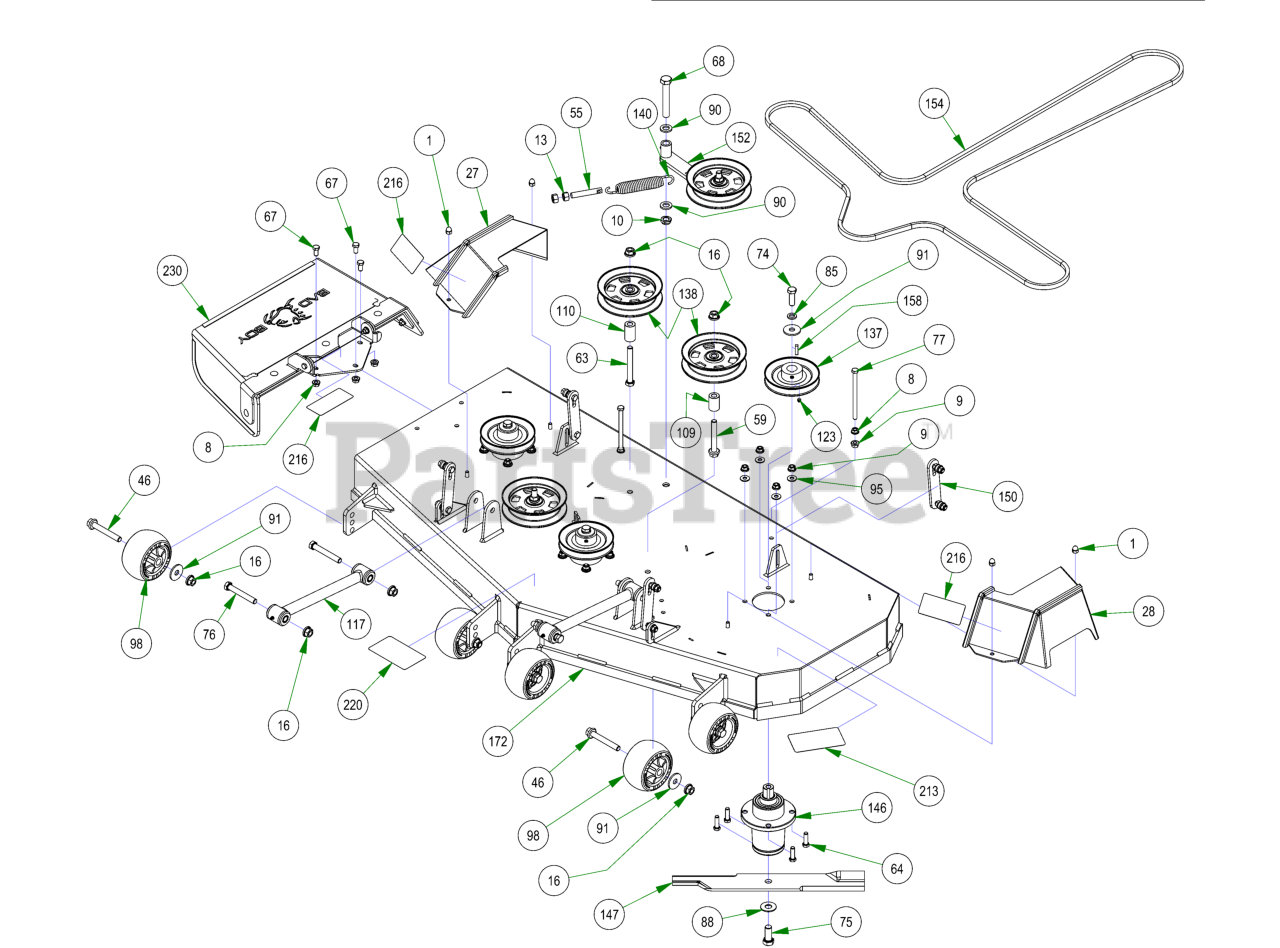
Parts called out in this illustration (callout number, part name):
1	5/16-18 ACORN NUT HIGH-CROWN ZC
8	3/8-16 HEX SERRATED FLANGE NUT HARD/ZINC
9	3/8-16 NYLON INSERT FLANGE LOCKNUT (GR.F) ZINC
10	5/8-11 NYLON INSERT JAM LOCKNUT ZINC
13	1/2-13 HEX NUT ZINC
16	1/2-13 NYLON INSERT FLANGE LOCKNUT ZINC
27	2021 Maverick 54”/60” RH Pulley Cover
28	2021 Maverick 54”/60” LH Pulley Cover
46	1/2-13 X 90MM HEX FLANGE BOLT W/SHOULDER (GR.8) ZINC
55	All Thread
59	1/2-13 X 3-1/2 HEX FLANGE BOLT (GR.8) ZINC
63	1/2-13 X 4 HEX CAP SCREW (GR.8) ZINC YELLOW
64	3/8-16 X 1-1/4 HEX CAP SCREW (GR.5) ZINC
67	3/8-16 X 3/4 HEX CAP SCREW (GR.5) ZINC
68	5/8-11 X 4 HEX CAP SCREW (GR.8) ZINC YELLOW
74	1/2-20 X 1-1/2 HEX CAP SCREW (GR.5) ZINC
75	5/8-18 X 1-1/2 HEX CAP SCREW (GR.8) ZINC YELLOW
76	1/2-13 X 3-1/2 HEX CAP SCREW (GR.5) ZINC
77	3/8-16 X 5-1/2 HEX CAP SCREW (GR.5) ZINC
85	1/2 SPLIT LOCKWASHER (GR.8) ZINC/YELLOW
88	5/8 USS FLAT WASHER (1-3/4" OD) GR.8 ZINC YELLOW
90	.635 ID X 1.120 OD X .140 THICK FLAT WASHER NYLON
91	1/2 BELLEVILLE WASHER (1-5/8 OD X .140 THK) ZINC
95	5/16 USS FLAT WASHER (7/8 OD) ZINC
98	Deck Wheel
109	.502 ID X .750 OD X 1.500 Long Spacer
110	1 3/4" Pulley Spacer
117	Hybrid Turnbuckle/Deck Locator
123	5/16-24 X 1/4 SOCKET SET SCREW (CUP PT) PLAIN
137	5.25" Deck Spindle Pulley
138	5-3/4 Idler Pulley
140	Deck Idler Spring
146	Spindle Assembly
147	54" Fusion Blade for ZT/Mav/Outlaw/Revolt
150	Deck Hanger Assembly
152	2017 MZ/ZT Deck Idler Assembly
154	B155.75 Deck Belt
158	1/4 X 1 SQ MACHINERY KEY 1018 STL PLN
172	2023 54" x 5" Deck
213	2018 54" Deck Decal
216	Danger Decal-Spindle/Discharge
220	Deck Belt Route Decal
230	Discharge Chute Assembly
